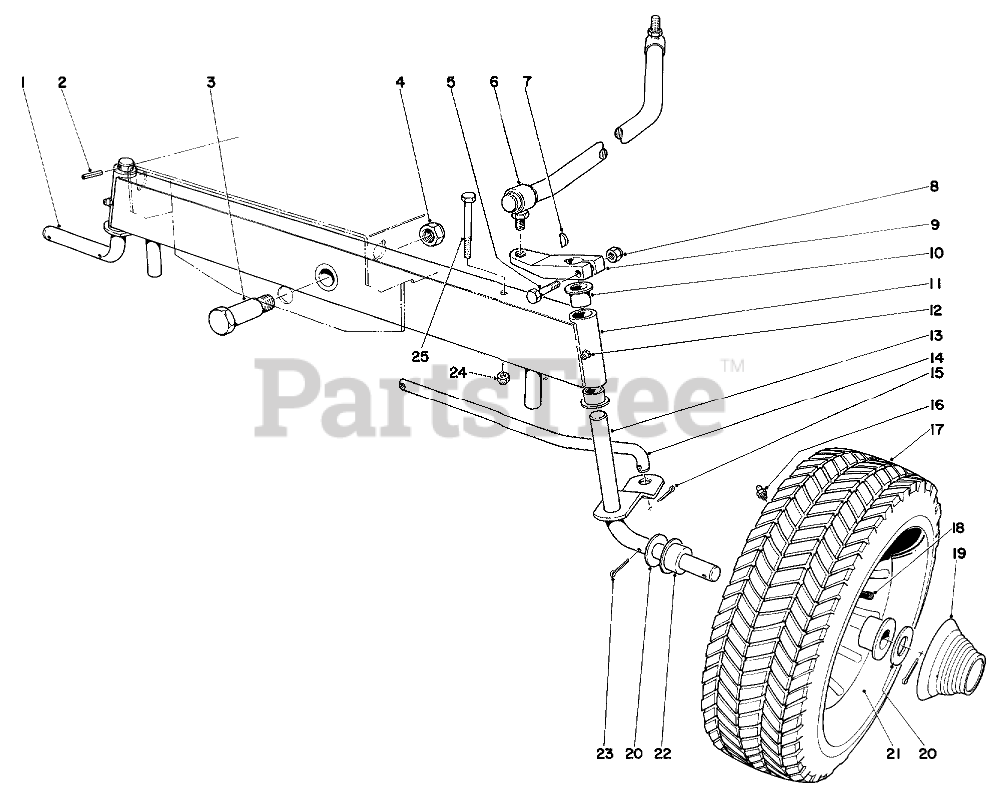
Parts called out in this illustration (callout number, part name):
1	Spindle
2	PIN-SPRING
3	Shoulder Bolt
4	1/2-13 CONELOCK NUT
5	SCREW-HH
6	Steering Rod
7	KEY-WOODRUFF
8	NUT-LOCK, CONE
9	Arm Steering
10	BUSHING-FLANGE
11	Front Axle
12	GREASE FITTING
13	Spindle
14	Tie Rod
15	PIN-COTTER
16	FITTING-GREASE
18	STEM-VALVE
19	FRONT HUB CAP
20	Washer
22	BUSHING
23	PIN-COTTER
24	NUT-LOCK, CONE
25	SCREW-HH
